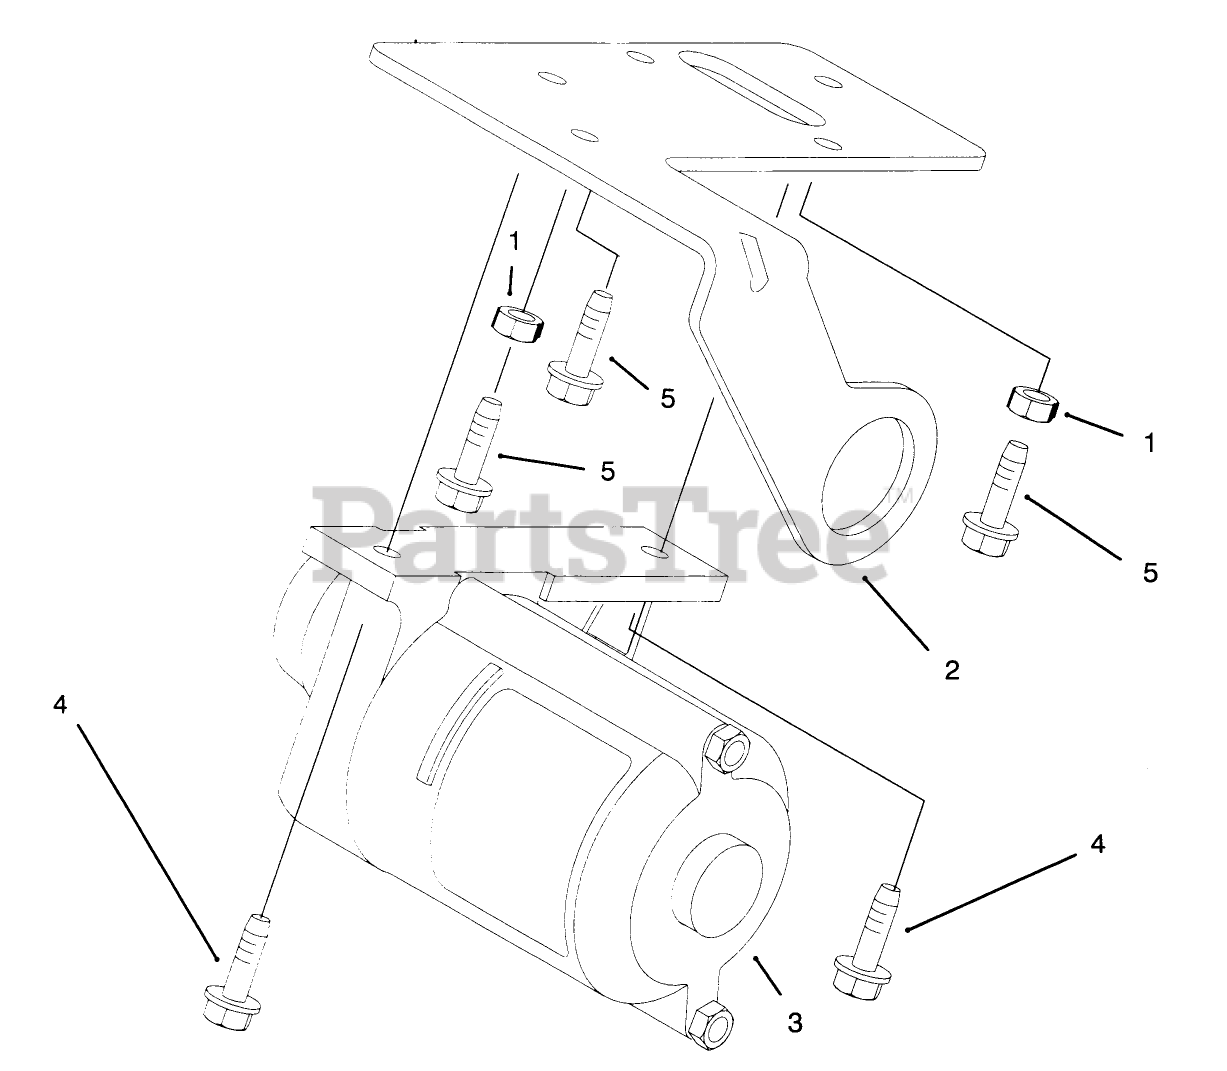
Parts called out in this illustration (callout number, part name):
1	NUT-LOCK, NI
2	MOUNTING BRACKET ASM
3	Motor-Starter
4	SCREW
5	Screw
